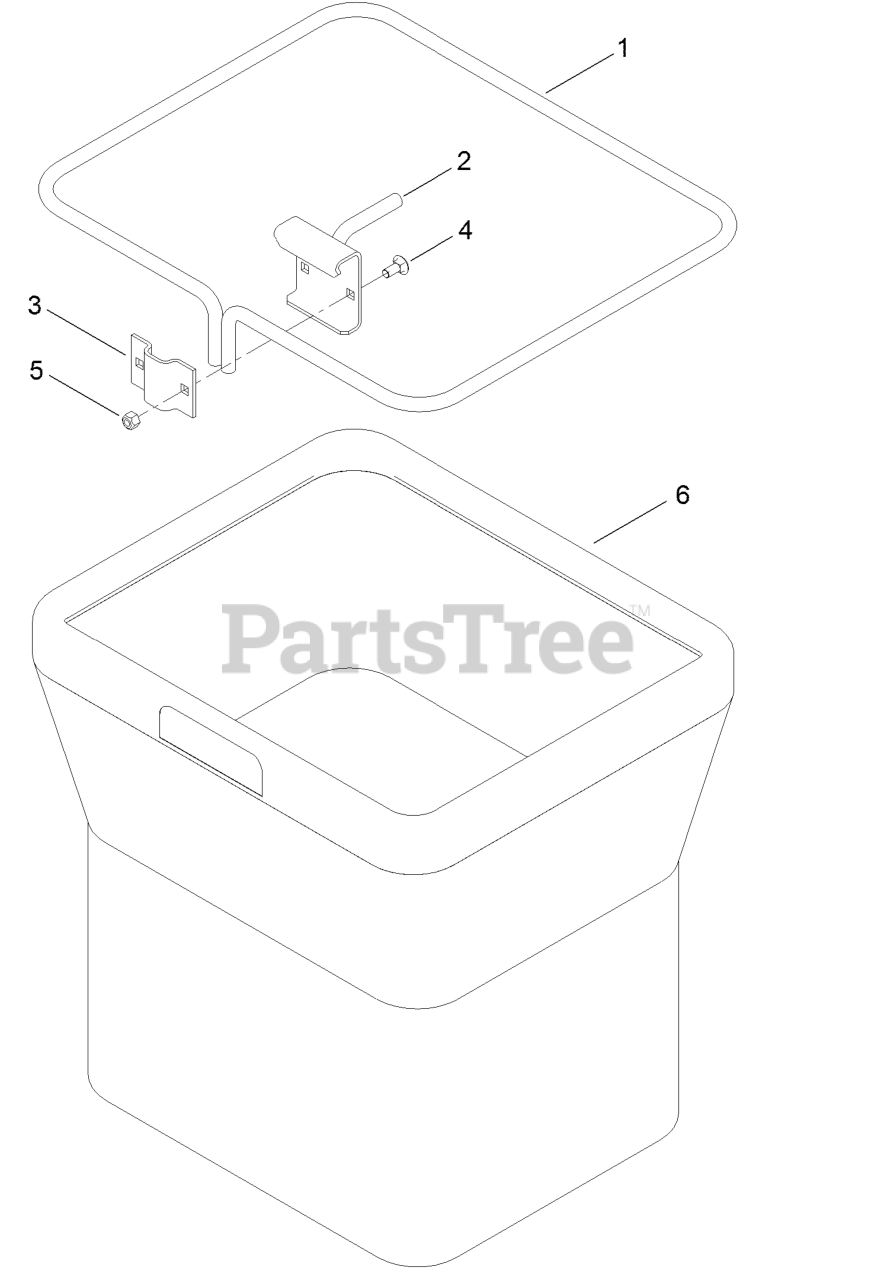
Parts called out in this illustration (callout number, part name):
1	FRAME-BAG
4	BOLT-CARR
5	NUT-LOCK, NI
